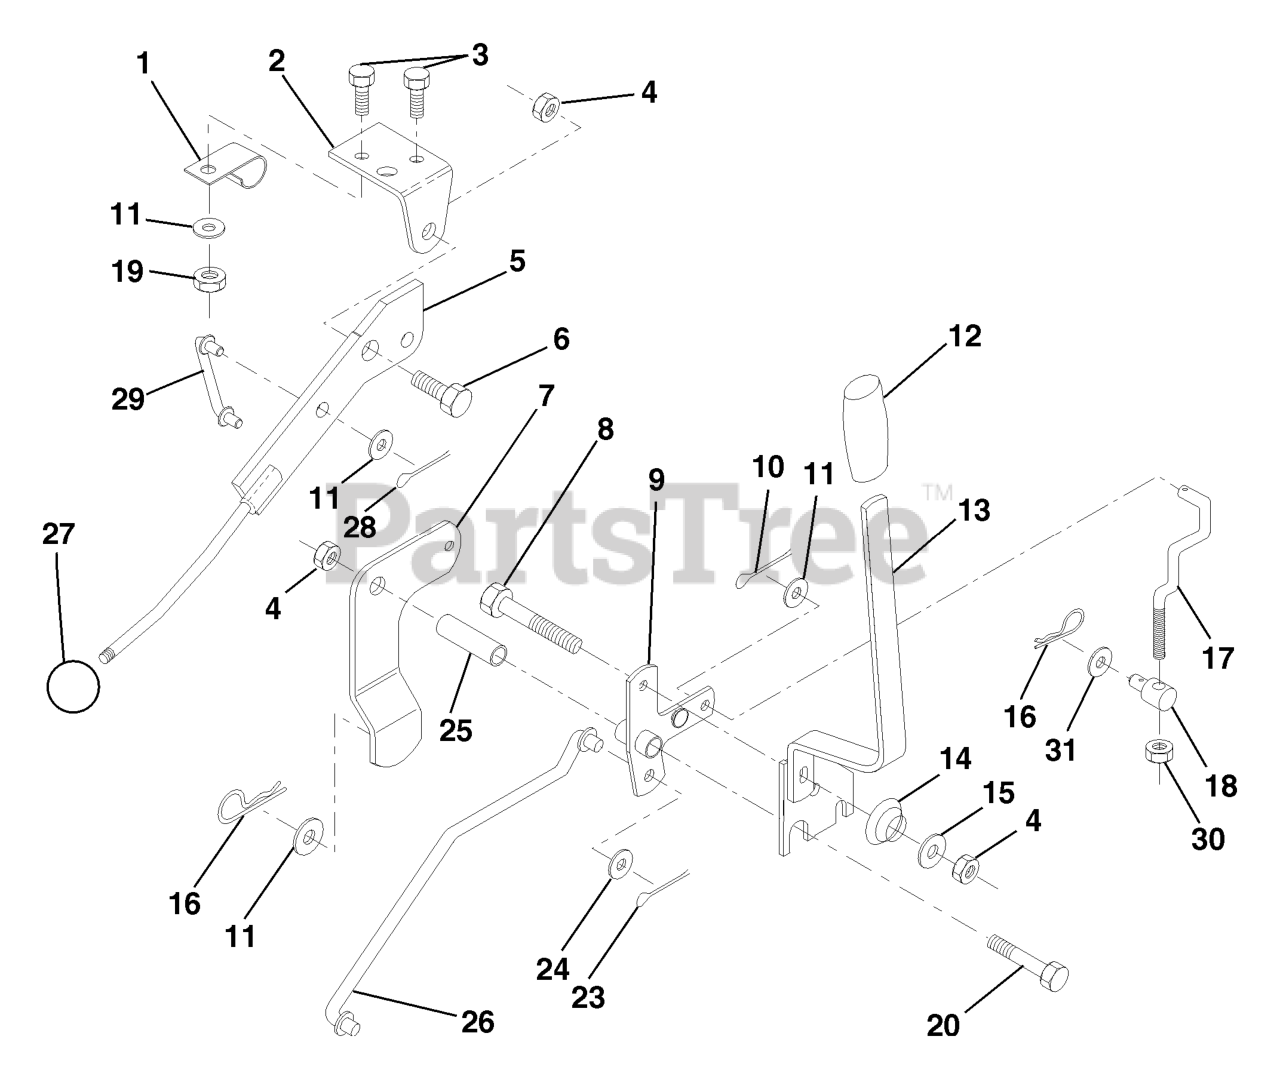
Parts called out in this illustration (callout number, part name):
1	CLIP,INSULATOR
2	BRKT CLUTCH
3	BOLT
5	CLUTCH LEVER
6	BOLT, SHOULDER LT
7	ASSEMBLY MOWER CLUTCH ARM
9	BELLCRANK,LIFT
10	COTTER PIN
11	WASHER
12	HANDLE GRIP
13	LIFT HANDLE ASSY
14	SPRING COMPRESSIO
15	WASHER T
16	SPRING TI
17	LINK LIFT FRT
18	TRUNNION.ADJUSTABLE.3/8-16
19	NUT.CROWNLOCK.1/4
23	PIN COTTER
24	WASHER GT
25	TUBE SPACER
27	KNOB T (3/8 HOLE)
28	COTTER PIN
29	LINK MOWER CLUTCH
30	NUT
31	WASHER
